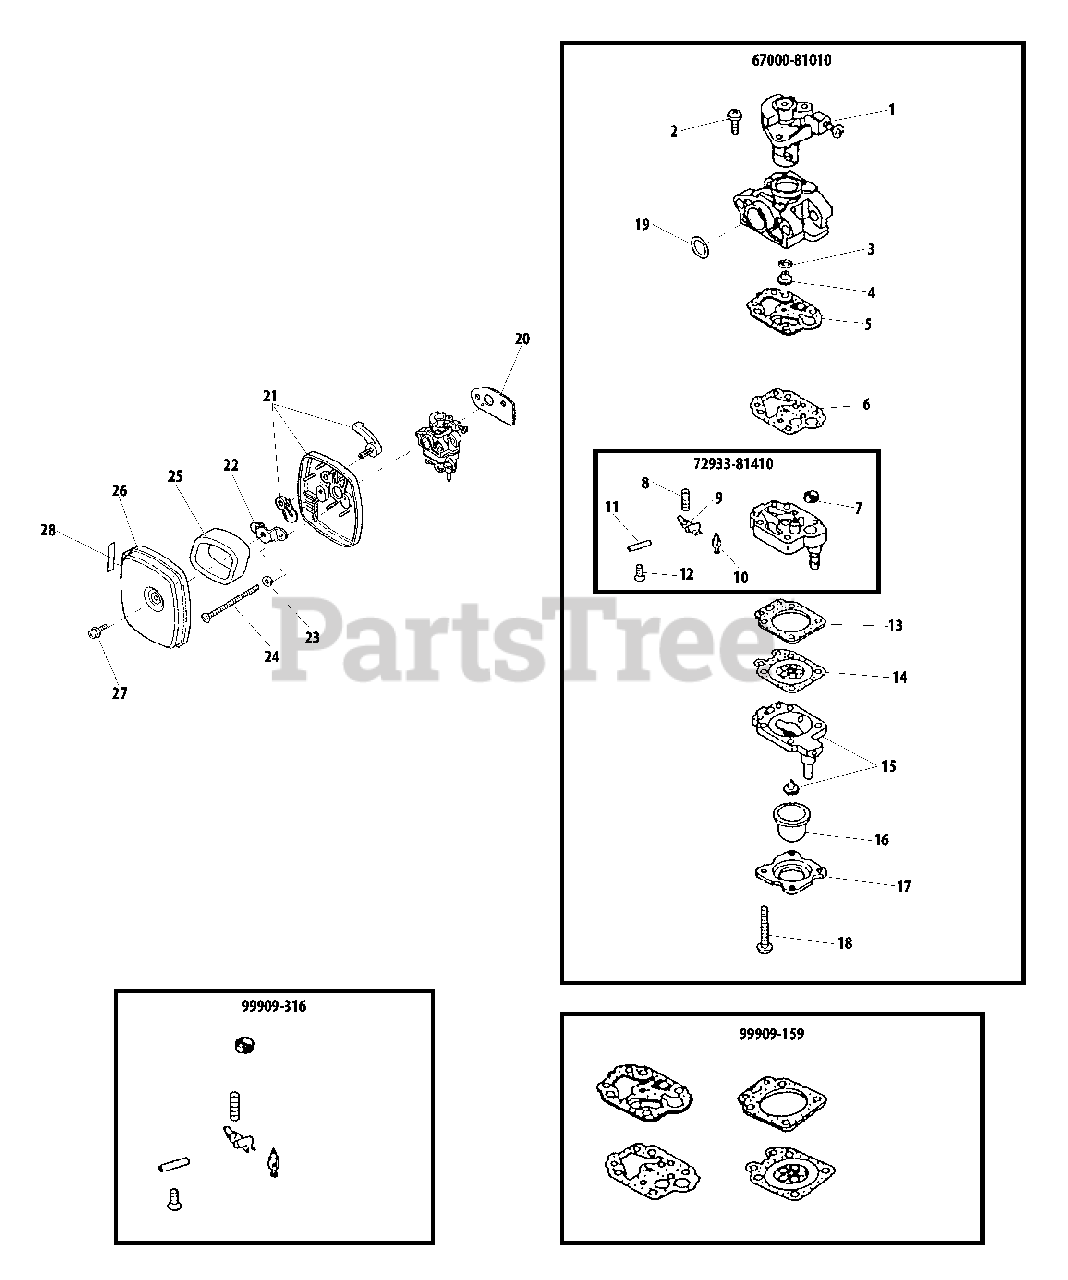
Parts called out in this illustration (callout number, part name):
1	THROTTLE VALVE ASSY
2	SCREW, THROTTLE COLLAR
3	O-RING
4	JET, MAIN #38
5	GASKET, PUMP
6	DIAPHRAGM, PUMP
7	SCREEN, FUEL INLET
8	SPRING, METERING LEVER
9	LEVER, METERING
10	VALVE, INLET NEEDLE
11	PIN, METERING LEVER
12	SCREW
13	GASKET, METERING DIAPHRAGM
14	DIAPHRAGM, METERING
15	BODY ASSY, PURGE
16	BULB, PURGE
17	RETAINER, PURGE BULB
18	SCREW
19	O-RING 15
20	GASKET, INTAKE
21	BASE ASSY, AIR FILTER
22	BRACKET
23	WASHER, FLAT 5.5×10×0.8
24	SCREW
25	FILTER
26	COVER, AIR FILTER
27	SCREW
28	LABEL, CHOKE
67000-81010	CARBURETOR
72933-81410	BODY ASSY, PUMP
99909-159	GASKET / DIAPHRAGM KIT
99909-316	VALVE KIT, INLET NEEDLE
